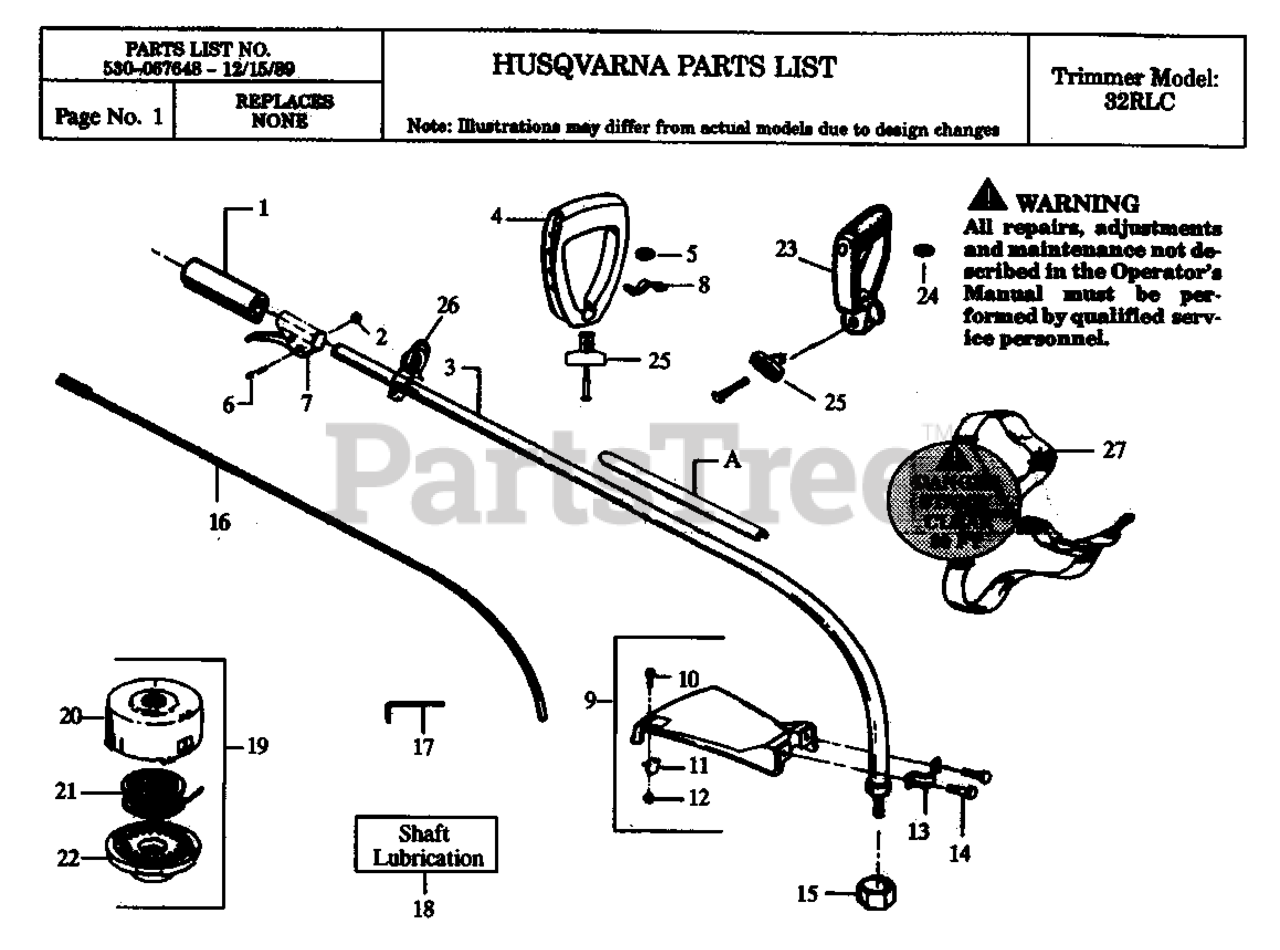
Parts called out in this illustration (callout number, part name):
1	GRIP-DRIVE SHAFT
2	LOCKNUT-HEX 10-24
3	LOCKNUT-HEX 10-24
4	ASSY-HANDLE
5	NUT (1/4-20)
6	SCREW-10-24 X 1" (UNC)
7	ASSY-THROTTLE HOUSING
8	CLAMP-ASSIST HANDLE
9	KIT-SHIELD (SERVICE) BLACK
11	LIMITER-LINE
12	LOCKNUT-(10-24)
13	BRACKET-SHIELD
14	SCREW-1/4-10X1-1/8 HEX
17	HEX KEY
18	GREASE-1/2 FL. OZ.
19	Cutting Head Ass'y.
20	Hub Ass'y.
21	Spool w/Line
23	Handle Ass'y.
25	KIT "T" HANDLE
26	ASSY-CLAMP HARNESS
27	STRAP-SHOULD.W/WARNING
A	Shaft Warning Decal
